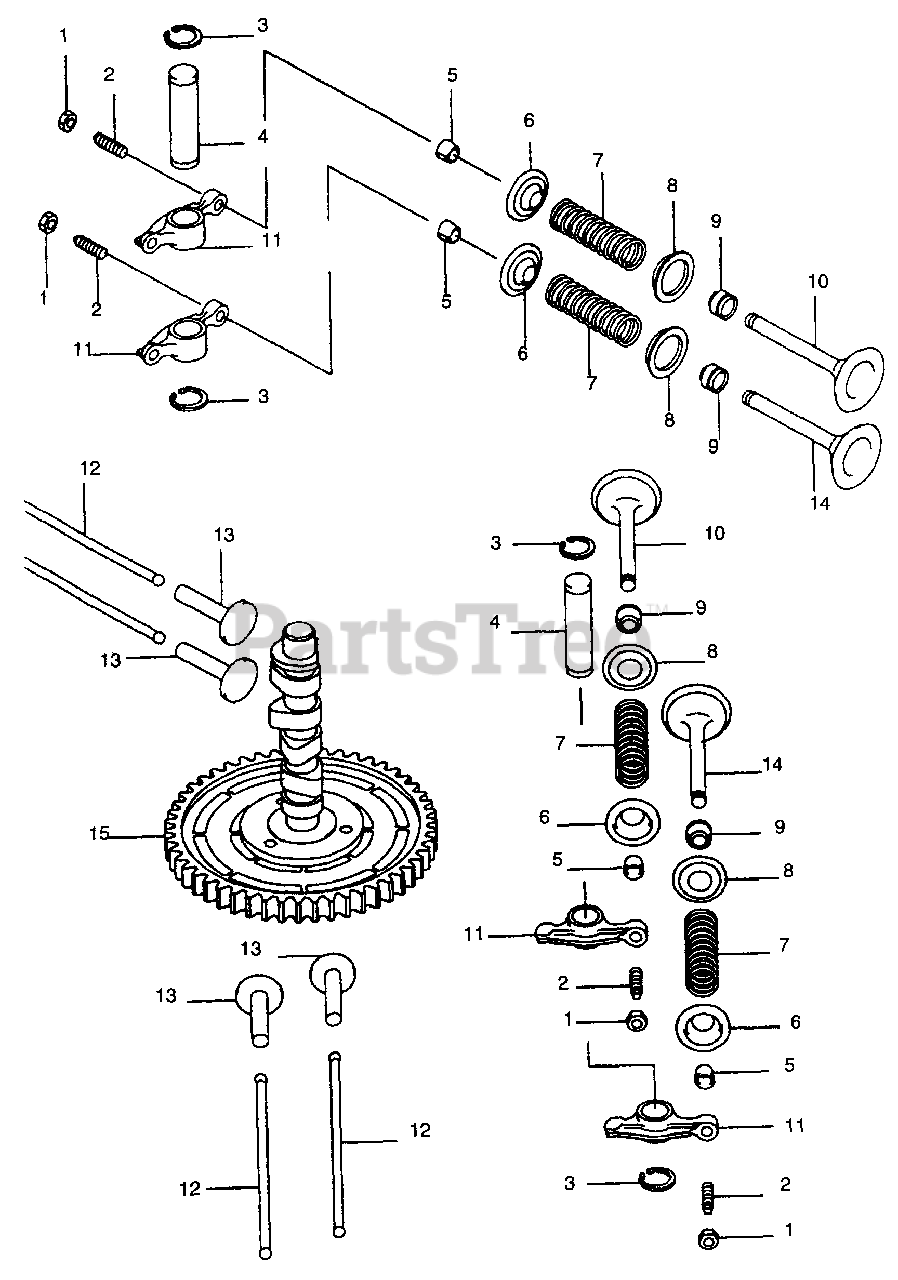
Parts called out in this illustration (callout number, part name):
6	Retainer Valve Spring
7	Engine Valve Spring
8	Retainer Spring
10	Intake Valve
14	Exhaust Valve
15	Camshaft-Comp.
